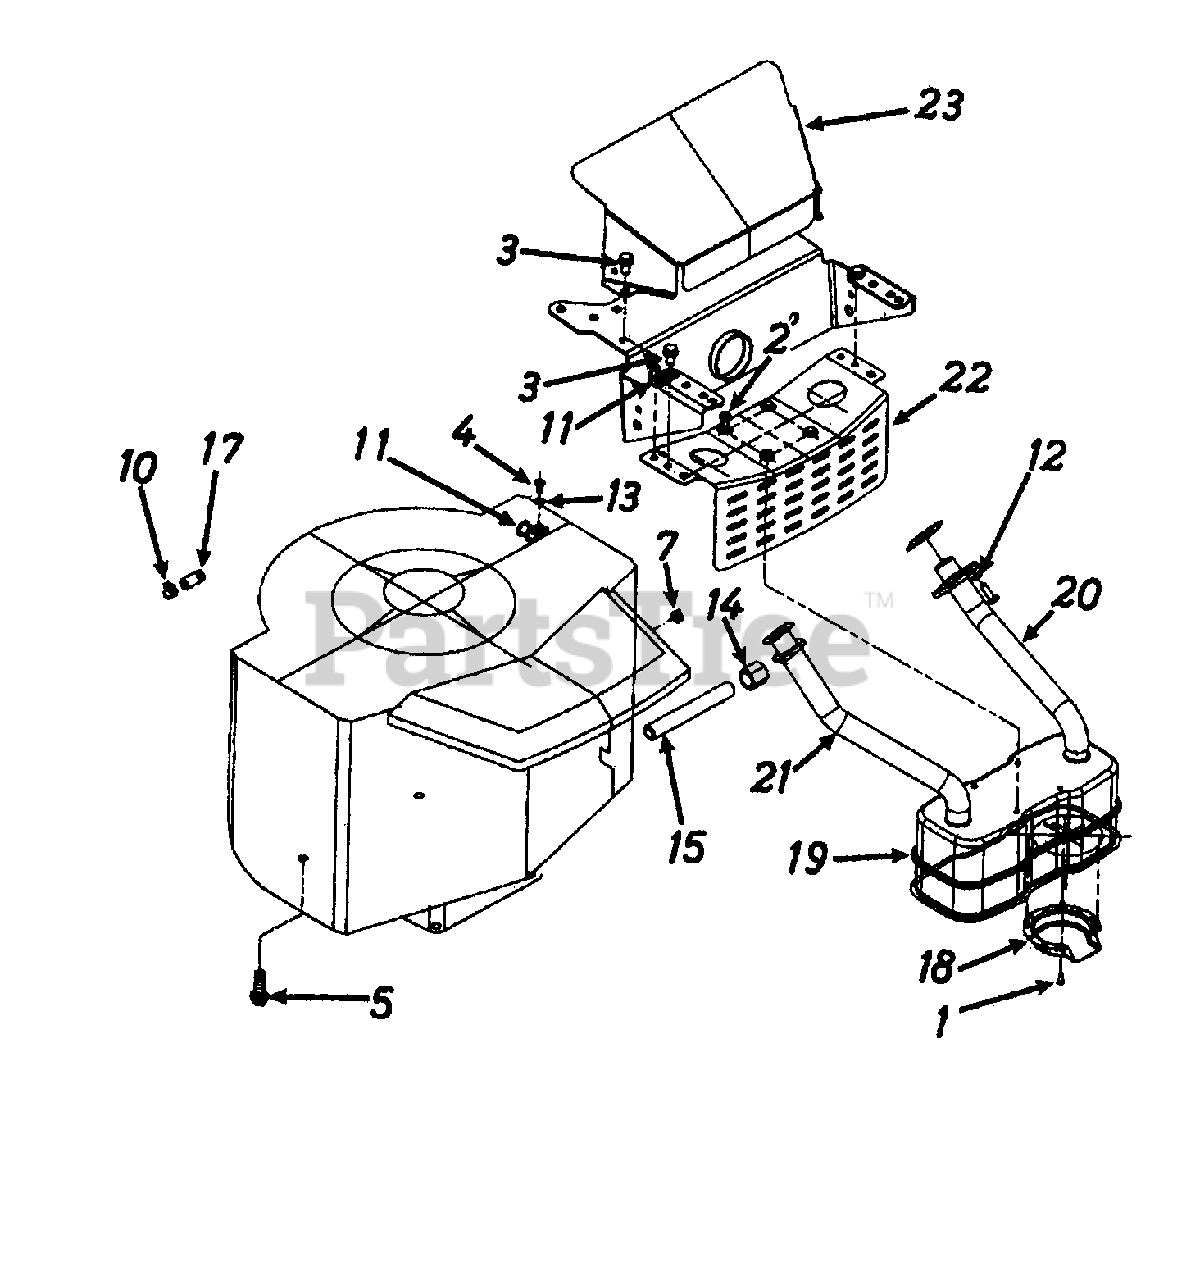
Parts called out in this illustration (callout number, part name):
1	Hex Tap Scr. #8-32 x .38" Lg.
2	Hex Wash. TT-Tap Scr. 1/4-20 x 5" Lg.
3	Hex Wash. TT-Tap Scr. 5/16-18 x .62" Lg.
4	Truss Mach. Scr. #10 x .5" Lg.
5	Hex Hd. Tap Scr. 3/8-16 x 1.25" Lg.
7	Hex Sems Nut 1/4-20 Thd.
10	Hose Clamp
11	Clamp
12	L-Wash. 1/4" I.D.
13	Fl-Wash..188" I.D. x .438" O.D.
14	Oil Drain Cap
15	Pipe Nipple 3/8 x 18 NPT.
17	Fuel Line 26" Lg.
18	Deflector: Muffler
19	Muffler
20	Exhaust Pipe-L.H.
21	Exhaust Pipe-R.H.
